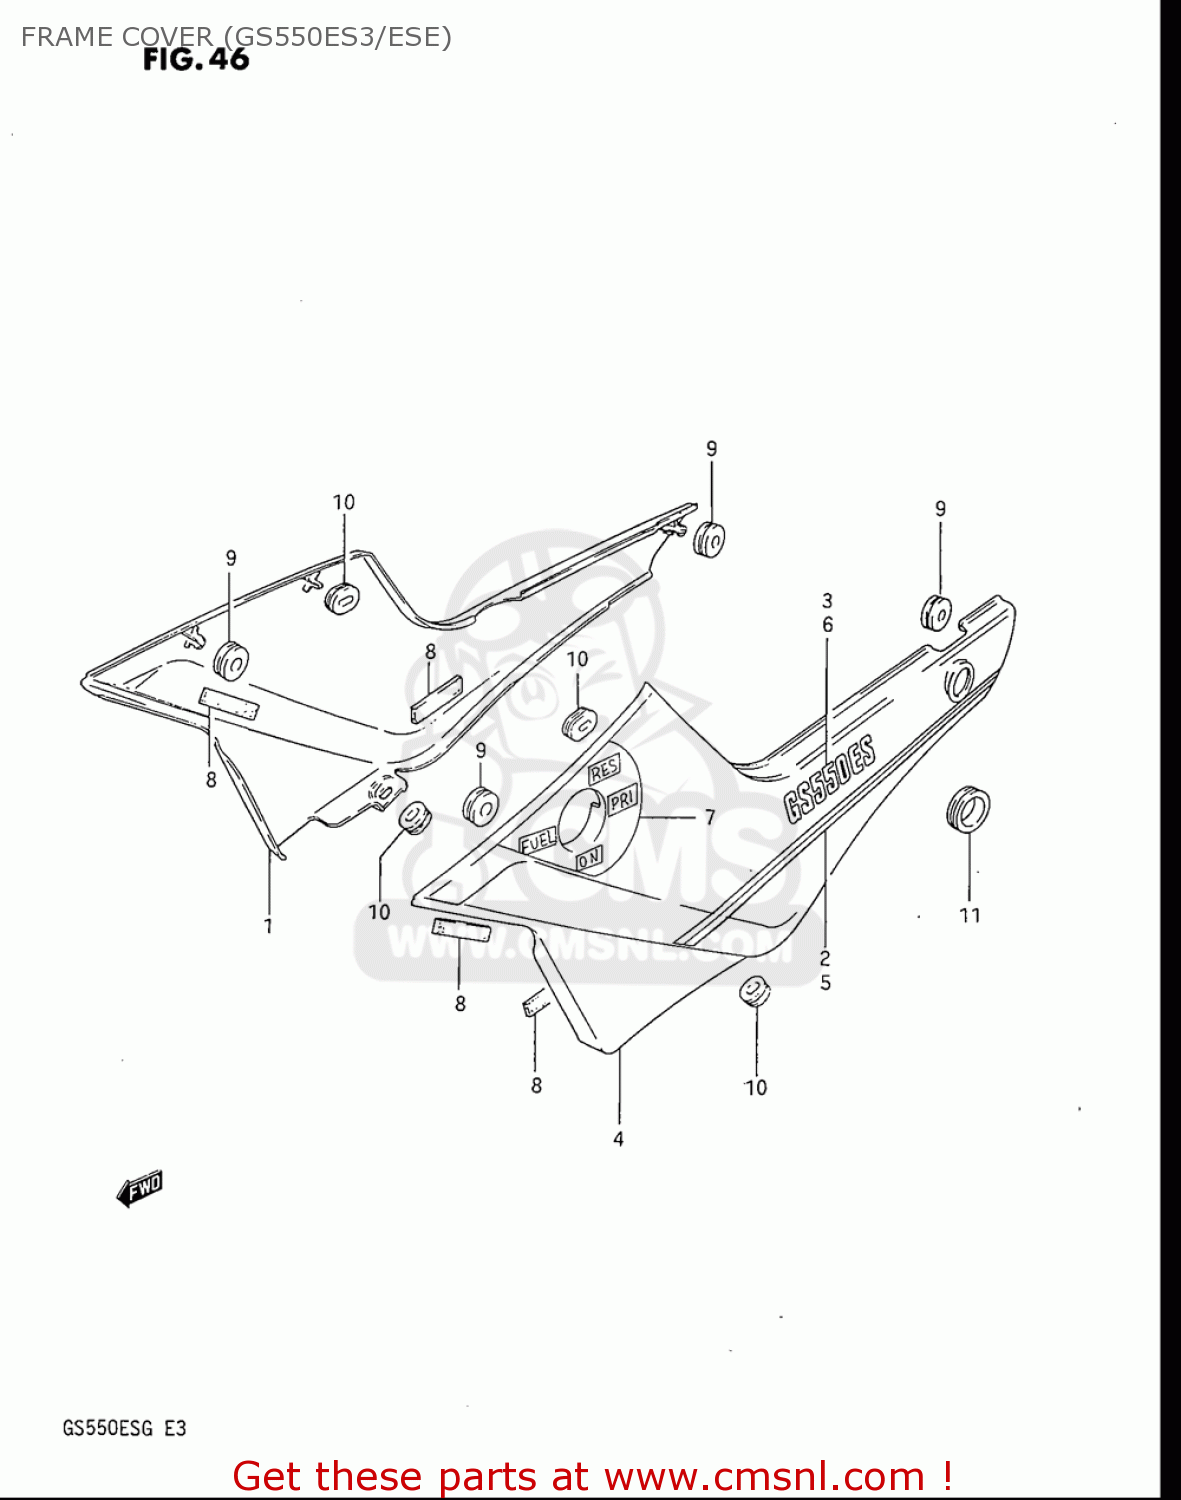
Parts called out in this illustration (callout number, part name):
1	COVER,FRAME,R
4	COVER,FRAME,L
8	RUBBER,FRAME COVER
9	CUSHION
10	CUSHION
11	GROMMET,SEAT LOCK HOLE
